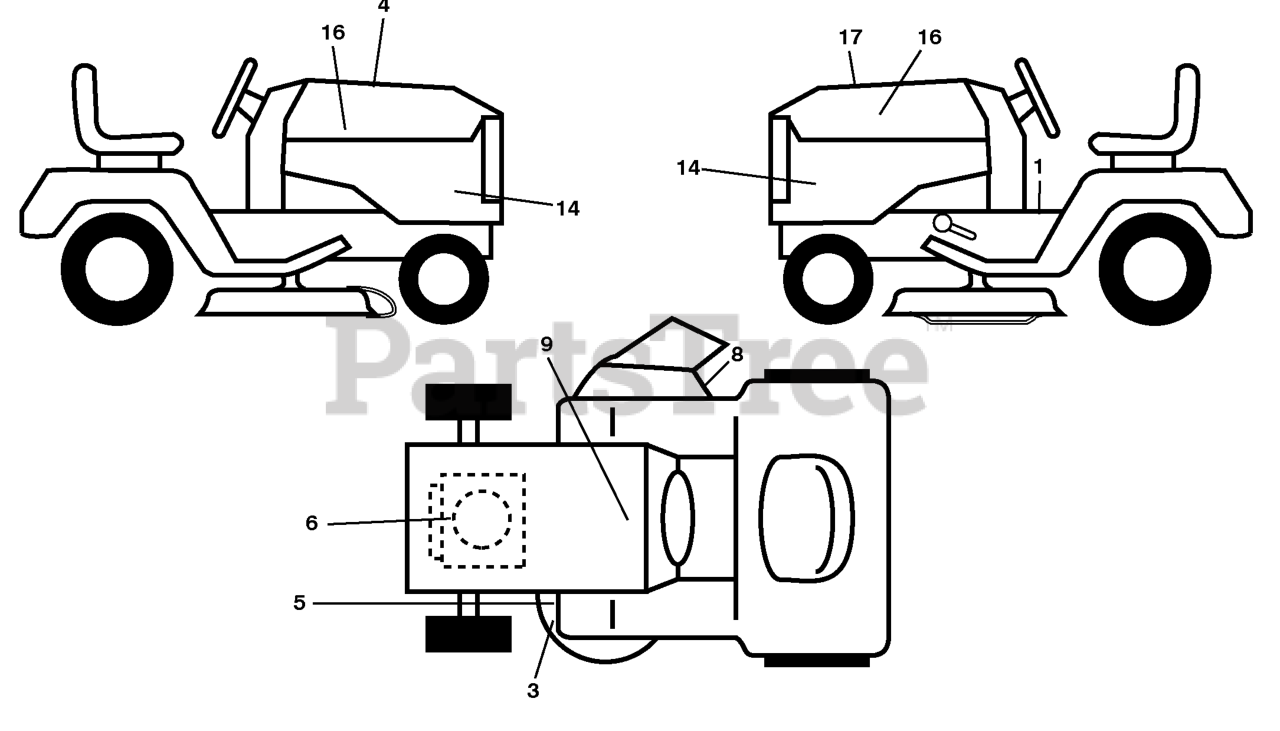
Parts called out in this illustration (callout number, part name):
1	DECAL.FENDER.WARNING.ENG
3	DECAL.WARN.KEEP.HAND.AWAY
4	DECAL.WARNING.CUST.RESP.E85.
5	DECAL.MOWER
6	Decal, Eng. HP
8	DECAL.MOWER.SCH.48/54
9	DECAL BTRY SYMBOLS
14	DECAL SDPNL.YTH24V54.B&S.HUSQ
16	RP.DECAL.BADGE.170MM.TEXTLOGO
